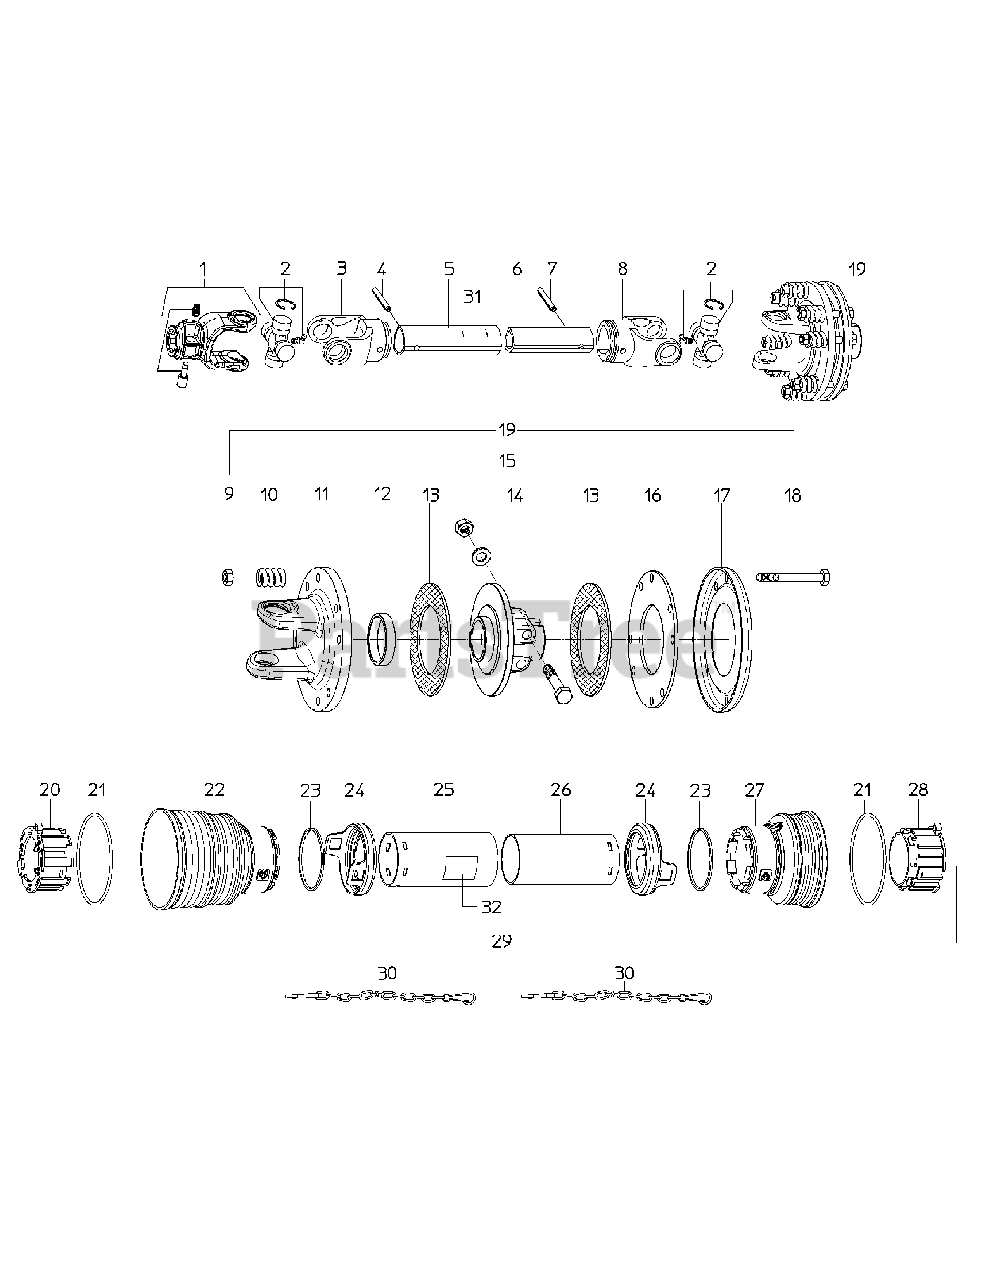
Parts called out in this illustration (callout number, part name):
1	PTO yoke
2	Cross & bearing
3	Female yoke
4	Roll pin Ø10x80
5	Female shaft
7	Roll pin Ø10x70
8	Male Yoke
9	Locking nut M10
10	Spring
11	Yoke slip clutch
12	Bushing
13	Friction disc
14	Body slip clutch
15	Nut, lock washer and bolt M12-1.25x70
16	Inner disc
17	Pressure disc
18	Hex bolt M10x80
19	Complete slip clutch
20	Outer tube locking ring
21	Stiffening ring
24	Safety sleeve
25	Female tube shield
26	Male tube shield
28	Inner tube locking ring
29	Complete shielding
30	Chain
31	Decal "DANGER - Guard missing, do not operate" outer tube
32	Decal "DANGER - Rotating driveline, keep away" outer shield
